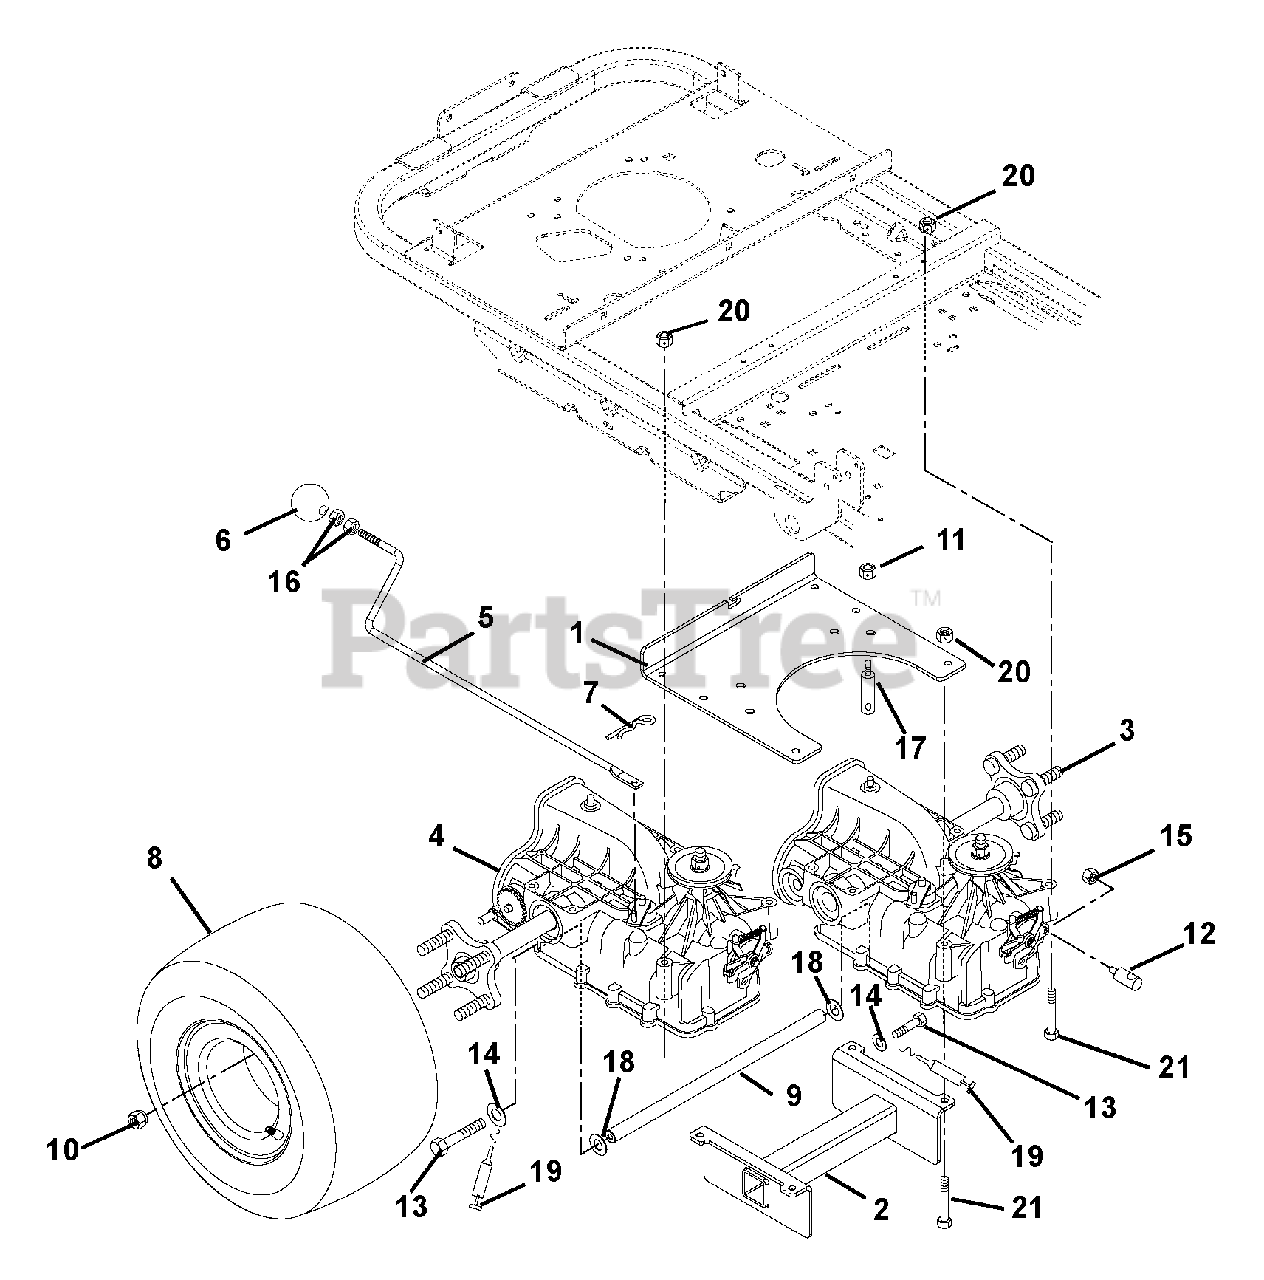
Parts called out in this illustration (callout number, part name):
1	BKT-TRANS AXLE SUPPORT
2	WLDMT-TRANS AXLE BRACE
3	IZT-LH (BIDIRECTIONAL RTN)
3	KIT, LH-BRAKE ARM IZT
4	IZT-RH (BIDIRECTIONAL RTN)
4	KIT,RH-BRAKE ARM IZT
5	ROD-DUMP IZT
6	KNOB, BALL 5/16-18 X 1.5
7	PIN-HAIR INT .08X.18X1.18 YWZC
8	ASSY-TIRE 9.5X18-2PLY
8	ASSY-TIRE 8.5X18 2PLY
9	ROD-AXLE BRACE
10	NUT-LUG .50-20 YWZC
11	@NUT-LK-NYL-FLG .38-16 YWZC
12	ROD PIVOT YWZC
13	@BLT-HEX .31-18X2.50 GR5 YWZC
14	@WSHR-LK .31X.078 REG YWZC
15	@NUT-LK-NYL-FLG .31-18 YWZC
16	NUT- JAM .312-18 YWZC
17	SHOULDER STUD
18	WSHR-FL-STL .328X.87X.179 YWZC
19	ADHSV SEALANT (BLUE) 250 ML
20	@NUT-LK-NYL-FLG .31-18 YWZC
21	@BLT-HEX .31-18X2.75 GR5 YWZC
